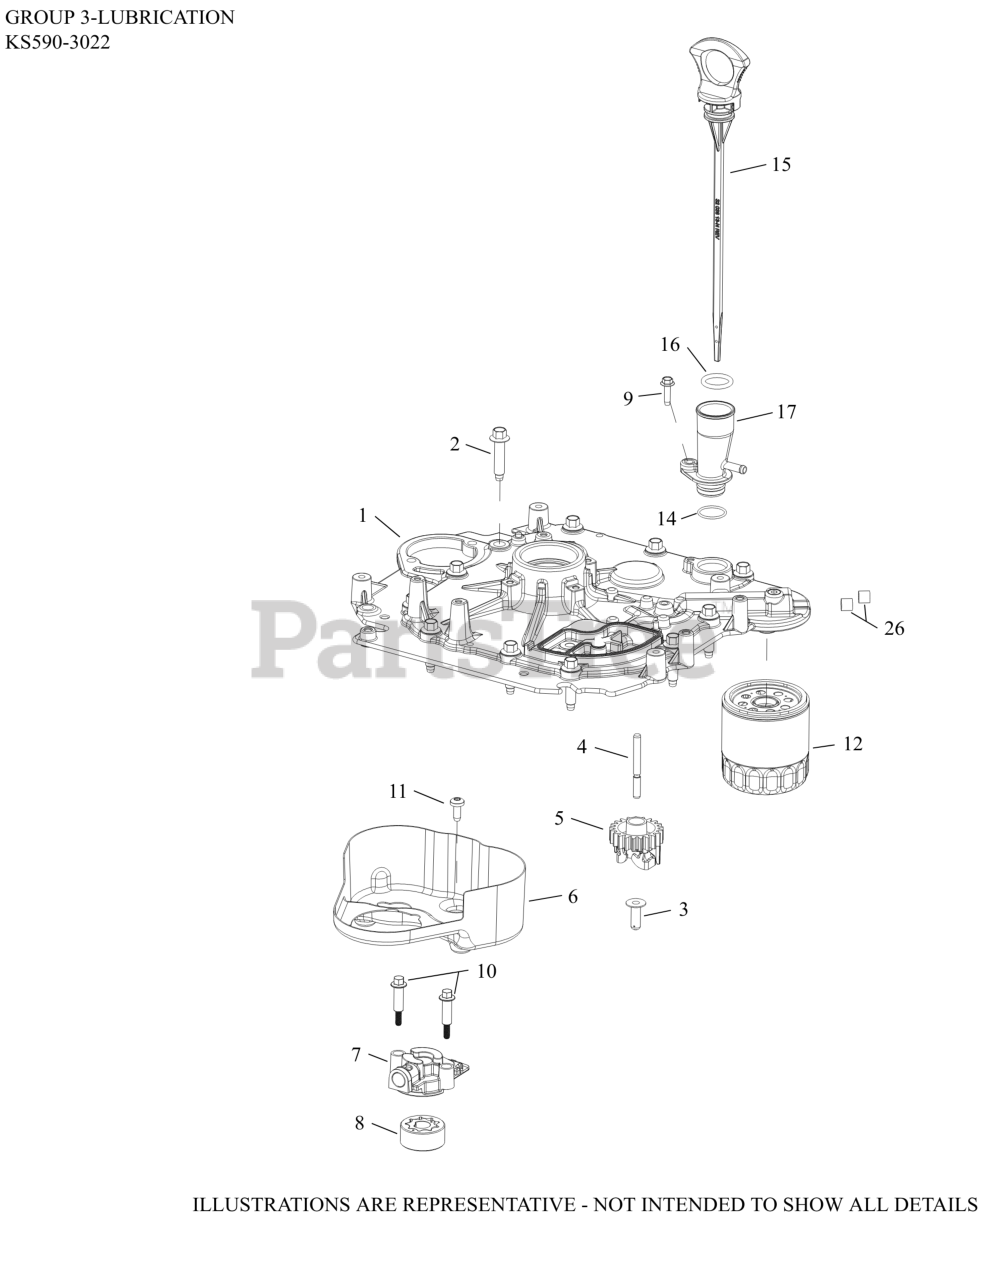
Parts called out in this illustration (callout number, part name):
1	PLATE, CLOSURE ASSY
2	SCREW, HEX FLANGE
3	PIN, GOVERNOR REGULATING
4	SHAFT, GOVERNOR CROSS
5	KIT, GOVERNOR GEAR
6	BAFFLE, OIL
7	HOUSING, OIL PUMP ASSY
8	PUMP ASSY, OIL
9	SCREW, THD FRM-USE 25 086 473-S
10	SCREW, SHOULDER THREAD FORMING
11	SCREW, THREAD FORMING
12	OIL FILTER
15	DIPSTICK, ASSY
17	TUBE, DIPSTICK ASSY
19	SEAL, OIL
26	PLUG, CTSK PIPE 1/8"
